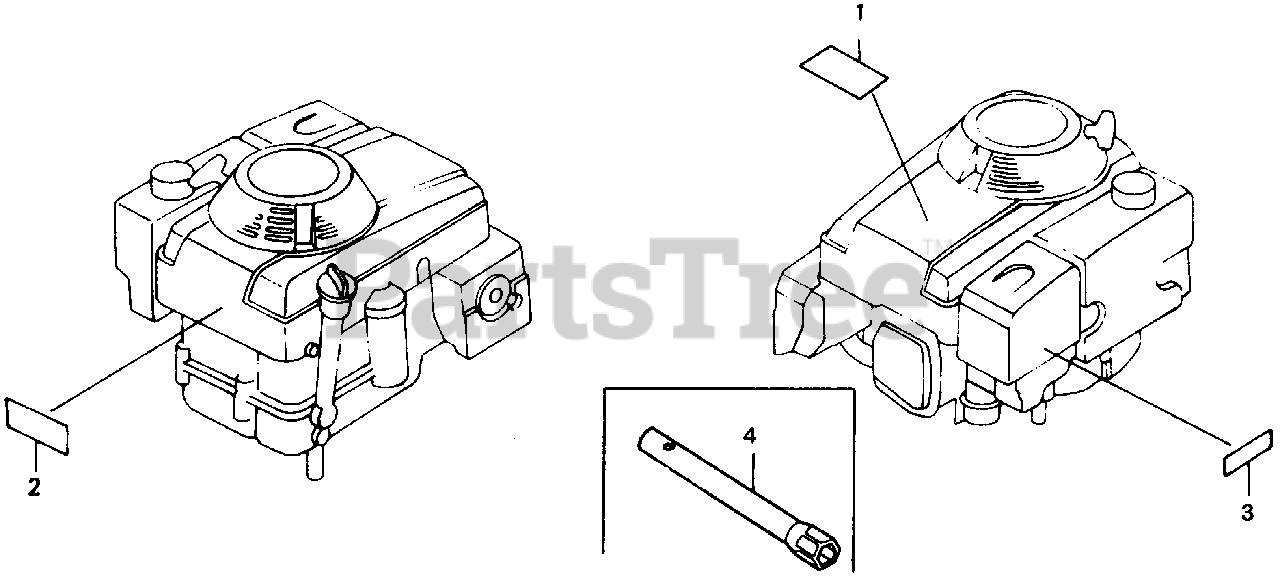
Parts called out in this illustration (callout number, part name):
1	EMBLEM, TOP COVER (ENGLISH)
2	LABEL, EMBLEM (H)
3	MARK, AIR CLEANER CAUTION
4	WRENCH, BOX (P21)
